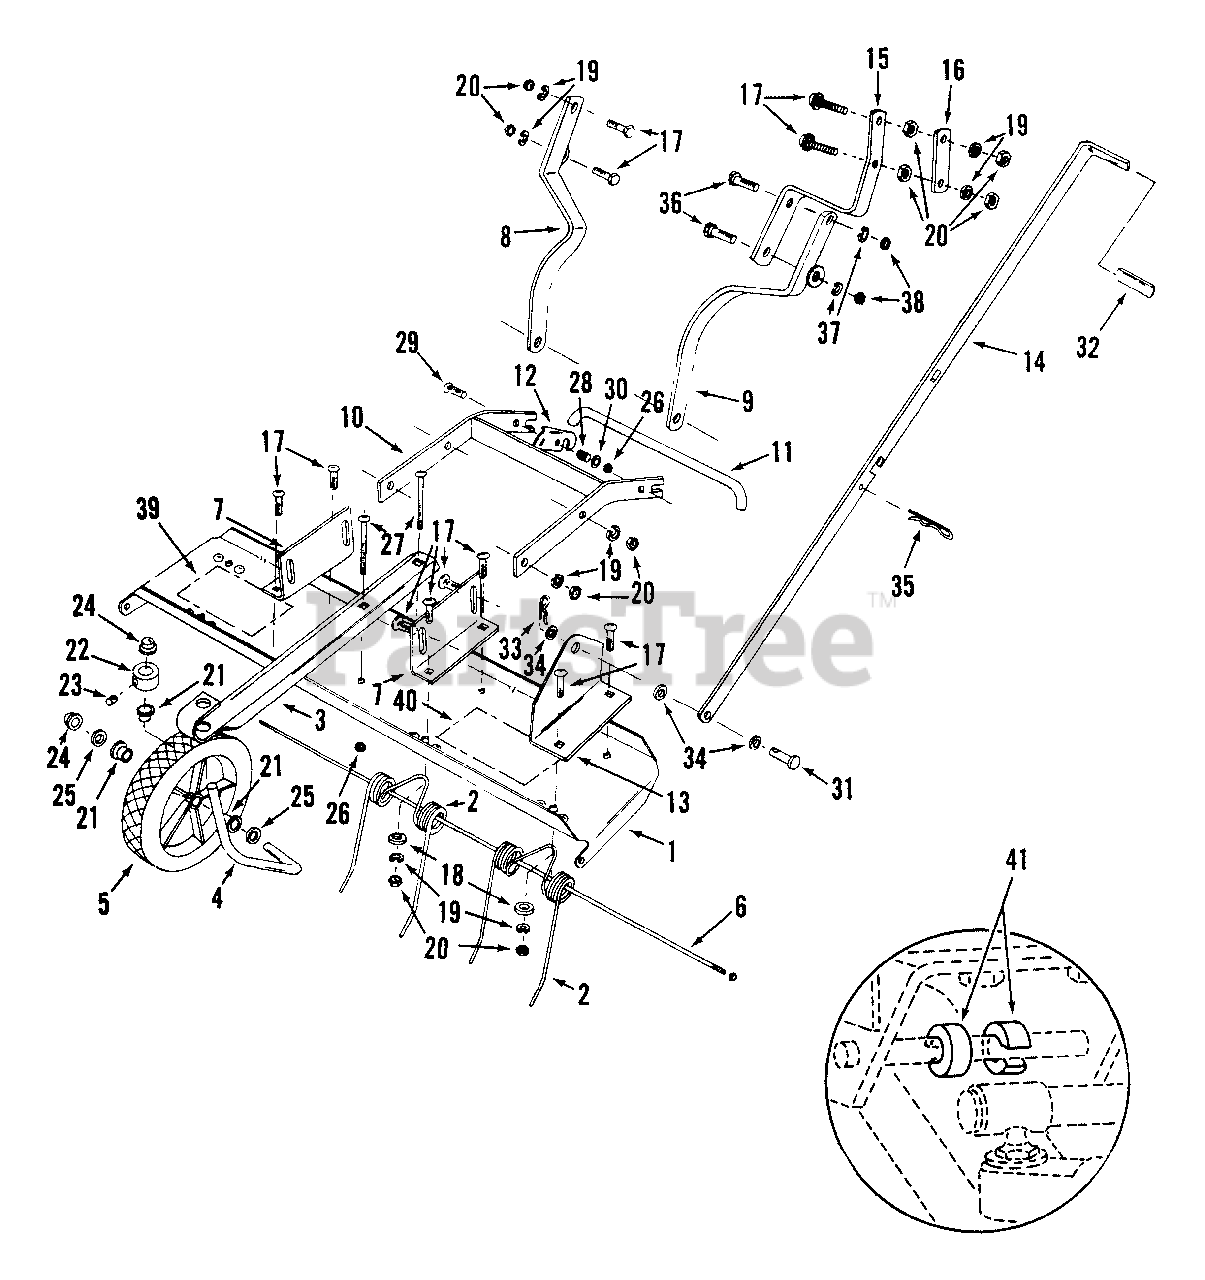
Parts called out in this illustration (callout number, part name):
1	TRAY, Tine
2	TINE, Thatching
3	SUPPORT, Wheel
4	AXLE
5	WHEEL, Gauge
6	ROD, Tine
7	BRACKET, Frame Mounting
8	BAR, Tractor Mounting, R.H.
9	BAR, Tractor Mounting, L.H.
10	ASSEMBLY, Main Frame Weldment
11	ROD, Mounting
12	LATCH, Frame Mount
13	BRACKET, Lift
14	HANDLE, Lift
15	BRACKET, Lift Handle Support
15	BRACKET, Lift Handle Support (LTD models)
16	STRAP, Handle Retaining
17	CARRIAGE BOLT, 5/16-18 x 1", Grade 5
18	WASHER, Reinforcing
19	WASHER, 5/16 Split Lock
20	NUT, 5/16-18 Hex, Grade 5
21	BEARING, Nyliner
22	BUSHING, Wheel Adjustment
23	SCREW, 5/16-18 x 1/4" Set
24	NUT, 1/2" Push
25	WASHER, 1/2 SAE
26	NUT, 1/4-20 Hex Top Lock
27	CARRIAGE BOLT, 1/4-20 x 1-3/4", Grade 2
28	SPRING, Compression
29	CARRIAGE BOLT, 1/4-20 x 1-1/4", Grade 5
30	WASHER, 1/4 SAE
31	PIN, 5/16 Lift
32	GRIP, Handle
33	COTTER, Hairpin
34	WASHER, 5/16 SAE
35	COTTER HAIRPIN
36	BOLT, 3/8-16 x 1-1/4", Grade 5
37	WASHER, 3/8 Lock
38	NUT, 3/8-16 Hex, Grade 5
39	DECAL, Logo
40	DECAL, Adjustment
41	RING, Spacer
